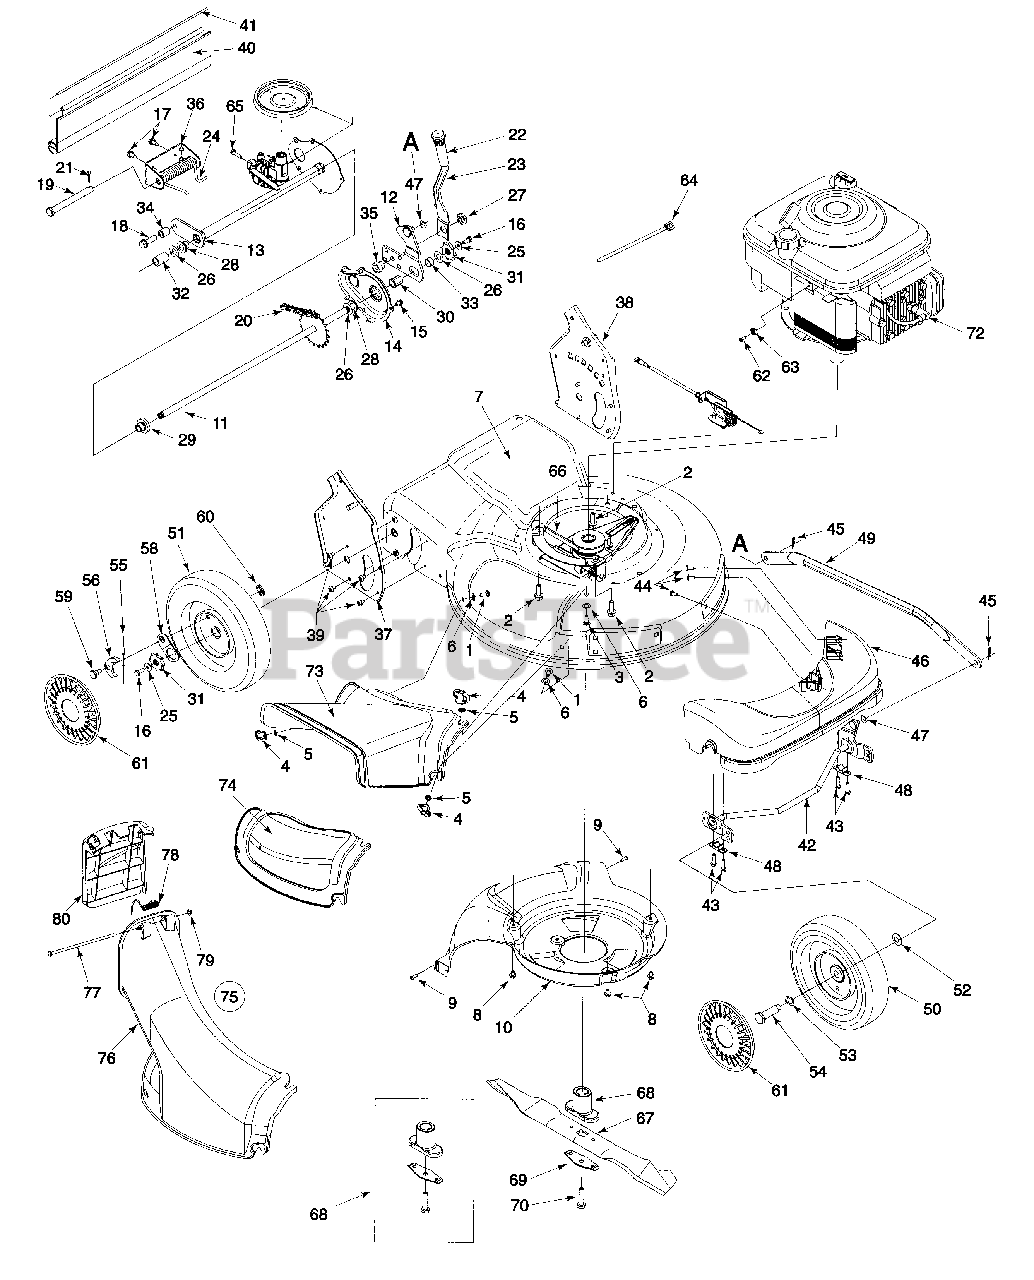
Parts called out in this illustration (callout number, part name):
1	Scr. Carr. 1/4-20 x .62
2	Scr. TT:3/8-18:1.00
3	Scr. 1/4-20 x .750
4	Wing Nut 1/4-20
5	Nut, Push .25 I.D. x .50 O.D.
6	Wash. Fl..334 I.D. x .62 x .03
7	Deck - 21"
8	Scr. TT. 1/4-20 x .375
9	Scr. HL. 1/2-14 x .750
10	Baffle
11	Rear Axle Ass'y
16	Cap Screw HH 1/4-20 x .620
17	Scr. AB 1/4-14 x .825
18	Scr. 3/8 116 x .25
19	Clevis Pin .50 Dia. x 4.82 Lg.
20	Chain-Endls. #48.500P x 24L
21	Cotter Pin .1250.D. x .75
23	Spring Lever
24	Torsion Spring
25	Bell Wash. .285 x .75 x .082
26	Fl. Wash. .508 I.D. 1.000 x .
27	Nut Shld. .825 Dia. x .165 Lg.
28	Hx . Flg. Brg. .506 I.D. x .590 L.
29	Hx . Flg. Brg. .506 I.D. x .715 L.
30	Hx . Slv. Brg. .504 I.D. x .830 L.
31	Wheel Rachet
32	Spa. .550 I.D. x 750 O.D.
33	Spa. .51 .D. x .70 O.D. x 38 L.
34	Spa. .385 x .624 x .700
35	Shld. Spa. .385 I.D. X .715 Lg.
38	Handle Brkt. Ass'y. L.H.
39	Scr. AB 1/4-14 x .500
40	Trail Shield
41	Trail Shield Wire
42	Fr. Axle Ass'y.
43	Hx Scr. Wash Hd. Hi.-Lo.
44	Scr. Torx, Truss Hi.-Lo.
45	Cotter Pin .072 x 1.12 Lg.
46	Fr. Axle Cover, Yellow
47	Bowed Washer
48	Bush. Block .505 Dia. x .62
49	Control Arm
50	Wheel 8 x 2 Link, Yellow
51	Wheel 9 x 2 Link Yellow, Slv.
52	Spr. Wash..401 x .870 x .063
53	Wave Wash .510 x .750 x .017
54	Shldr Scr .498 x 1.445 x 3/8-16
55	Spring, Ratchet, Plastic
56	Pawl- R.H.
56	Pawl - L.H.
58	Ratchet Pawl Plate
59	Scr. Shld. .340 x .285
60	Top Lock Tab Weld Nut 1/4-20
61	Hubcap -Yellow
62	Screw .620 Hx . Sit. Wsh.
63	Casing Clamp, Throttle
64	Cable Tie
65	Hex Scr. 5/16-18
66	Belt
67	21" Mulching Blade
68	Blade Adapter Kit
69	Blade Bell Suport
70	Hex Bolt 3/8-24 x 2.5"Lg.
72	Spark Plug Insulator
73	Side Discharge Chute
74	Mulch Cover
75	Chute Ass'y
76	Discharge Chute
77	Pivot Rod
78	Torsion Spring
79	Push Cap
80	Chute Door
